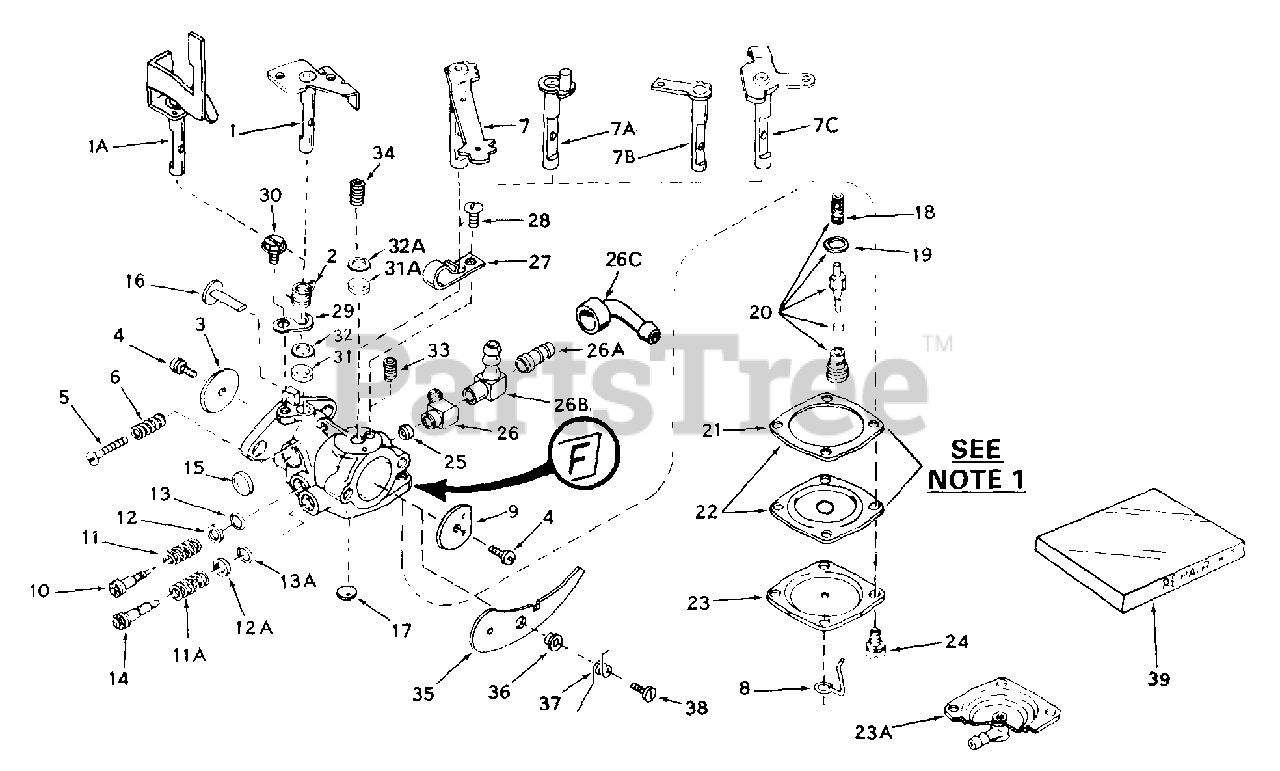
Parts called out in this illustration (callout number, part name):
1	"Shaft & Lever Assy., Throttle
2	Spring, Throttle return
3	Shutter, Throttle
4	Screw, Throttle & Choke shutter
5	Screw, Idle regulating
6	Spring, Idle regulating screw
7B	Shaft & Lever Assy., Choke
9	Shutter, Choke
10	Screw, Idle adj.
11	Spring, Adj. screw
11A	Spring, Adj. screw
12	Washer, Adj. screw
12A	Washer, Adj. screw
13	"O" Ring, Adj. screw
13A	"O" Ring, Adj. screw
14	Screw, Main adj. (.0225 dia. hole)
15	Plug, Welch
16	Element, Pump
17	Plug, Welch
18	Spring, Valve
19	Gasket, Valve seat
20	Inlet Needle, Seat, Gasket & Spring
21	Gasket, Diaphragm
22	Diaphragm Assy.
23	Cover, Diaphragm
24	Screw, Cover
25	Valve, Check
26	Fitting, Fuel inlet
27	Spring, Detent
29	Retainer, Throttle shaft
39	Repair Kit
